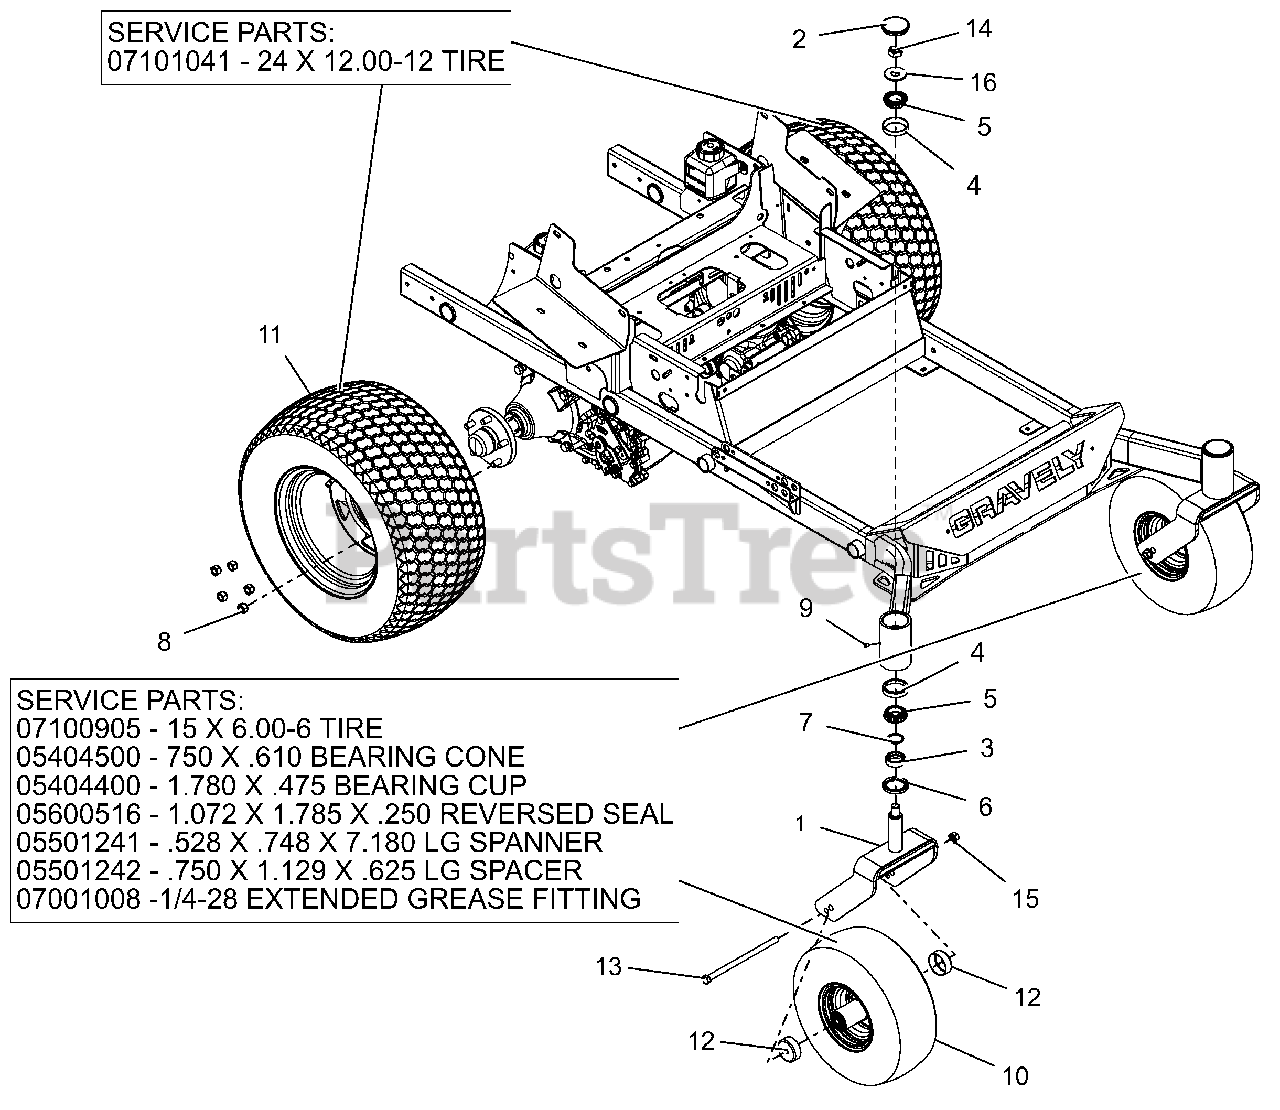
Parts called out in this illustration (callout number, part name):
1	CASTER FORK WMT - RED
2	CAP, DUST
3	SPCR, FRONT CASTER FORK
4	BRG-CUP 2.328X.465
5	BRG-CONE 1.25X.66
6	SEAL, OIL 1.75 X 2.332 X .312
8	WHEEL NUT .500-20 YZ
9	FTG, .25-28 FLUSH MNT GREASE
10	ASM, WHL/TIRE 15X6.00-6 SMOOTH
11	ASM, WHL/TIRE 24X12.00-12 K500
11	TIRE, 24 X 12.00-12
12	SHIELD, WHEEL BEARING
12	TIRE, 15X6-6 SMOOTH
12	BRG-CONE .750X.61
12	BRG-CUP 1.781X.475
12	SEAL,1.072X1.785X.250 REVERSED
12	SPANNER, .528X.748X7.18 LG
12	SPACER, .750X1.129X.625 LG
12	GREASE FITTING 1/4-28 EXTENDED
13	@BLT-HEX .50-13X9.00 GR5 YWZC
14	NUT-JAM TOPLK .75-16 YWZC
15	@NUT-LK-TOP-FLG .50-13 YWZC
16	@WSHR-FL-STL.812X2.00X.148YWZC
